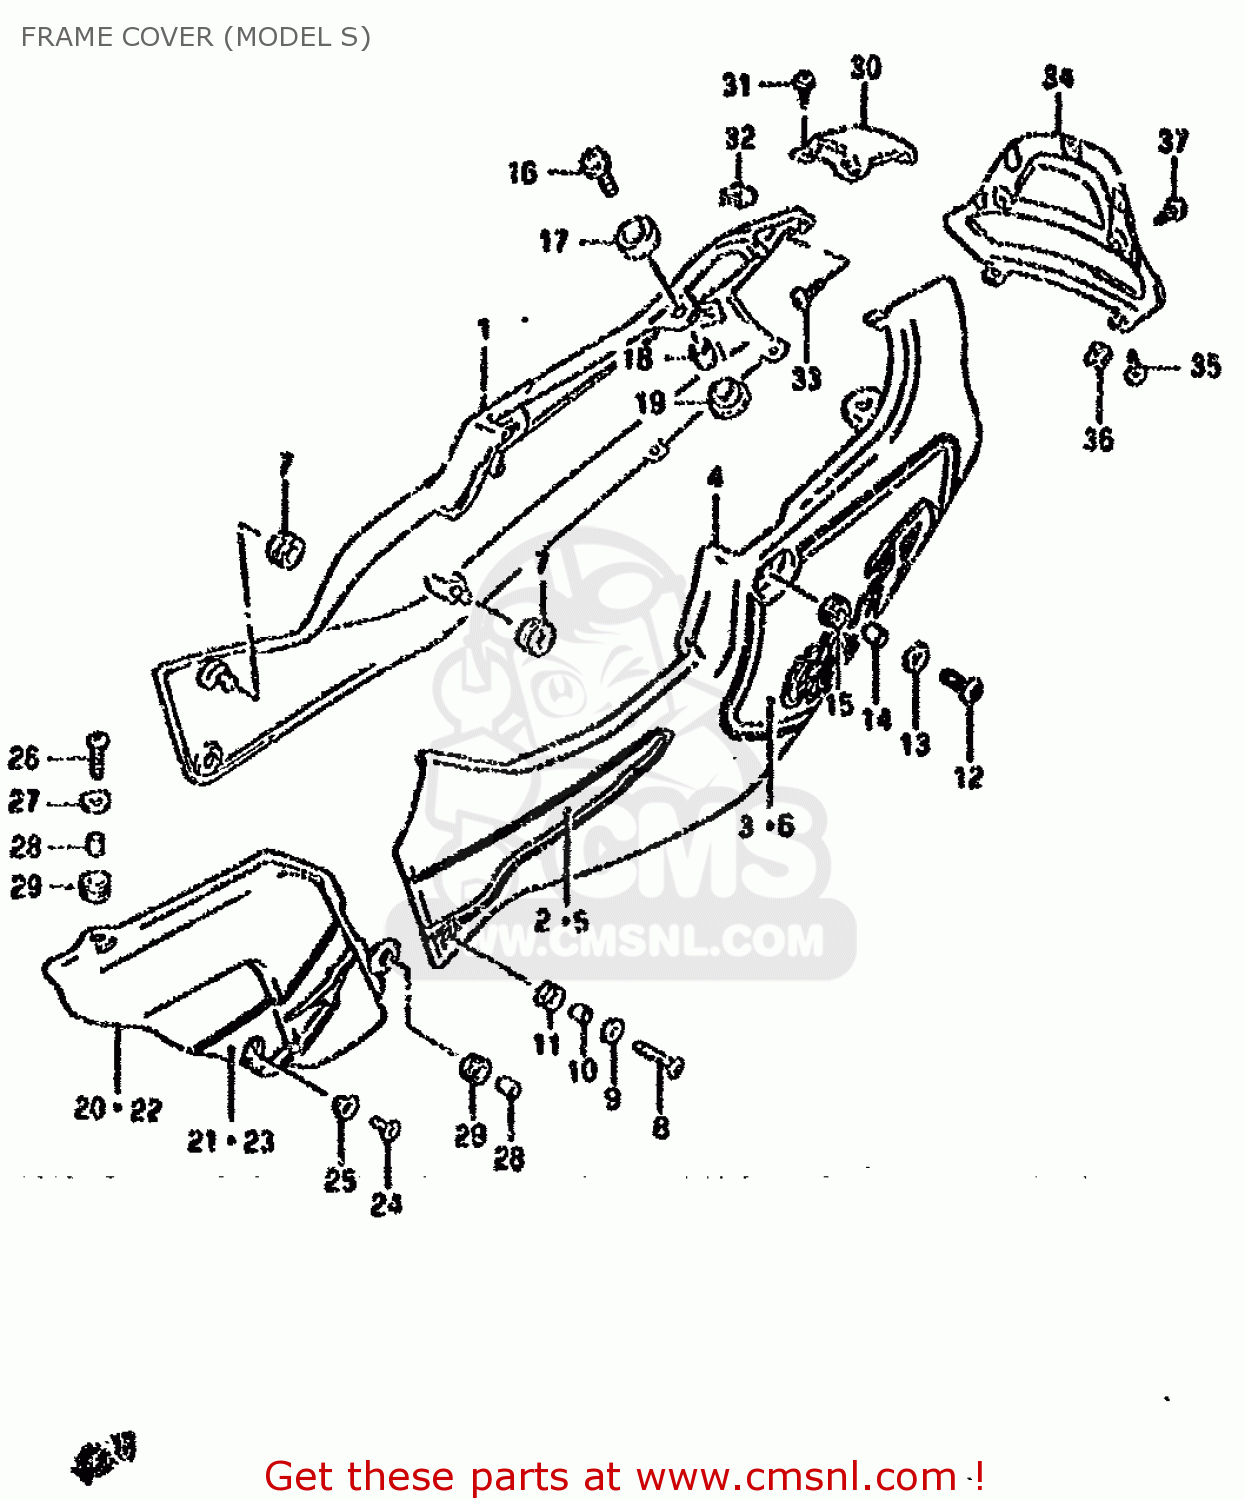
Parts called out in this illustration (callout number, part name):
1	COVER ASSEMBLY,FRAME,RIGHT
2	TAPE,FRAME COVER,RIGHT
3	TAPE,FRAME COVER ZECKE
4	COVER ASSY,FRAME,L(WHITE)
5	TAPE,FRAME COVER,LEFT
6	TAPE,FRAME COVER STICKER
7	CUSHION
8	SCREW(6X30)
9	WASHER
10	SPACER (6.1X9X9)
11	CUSHION
12	SCREW(6X20)
13	WASHER(6.5X22X1.6)
14	SPACER (6.3X9.1X6.7)
15	CUSHION
16	SCREW(6X30)
17	CUSHION,TAIL COVER UPR
18	SPACER (6,8X10X9.4)
19	CUSHION,FRAME COVER LWR
20	COVER ASSEMBLY,FRAME BODY
21	TAPE,FRAME COVER BODY
22	COVER ASSEMBLY,FRAME BODY
23	TAPE,FRAME COVER BODY
24	SCREW(5X14)
25	WASHER
26	SCREW(6X25)
27	WASHER
28	SPACER (6.1X9X9)
29	CUSHION
30	COVER ASSY,FRAME CTR
31	SCREW
32	NUT
33	SCREW(5X14)
34	COVER,FRAME RR
35	SCREW 5X12
36	NUT
37	NUT
38	SCREW
39	COVER,FRAME RR
40	SCREW(5X12)
41	NUT
42	NUT
43	COVER,FRAME RR
44	SCREW(5X12)
45	NUT
46	SCREW
47	NUT
